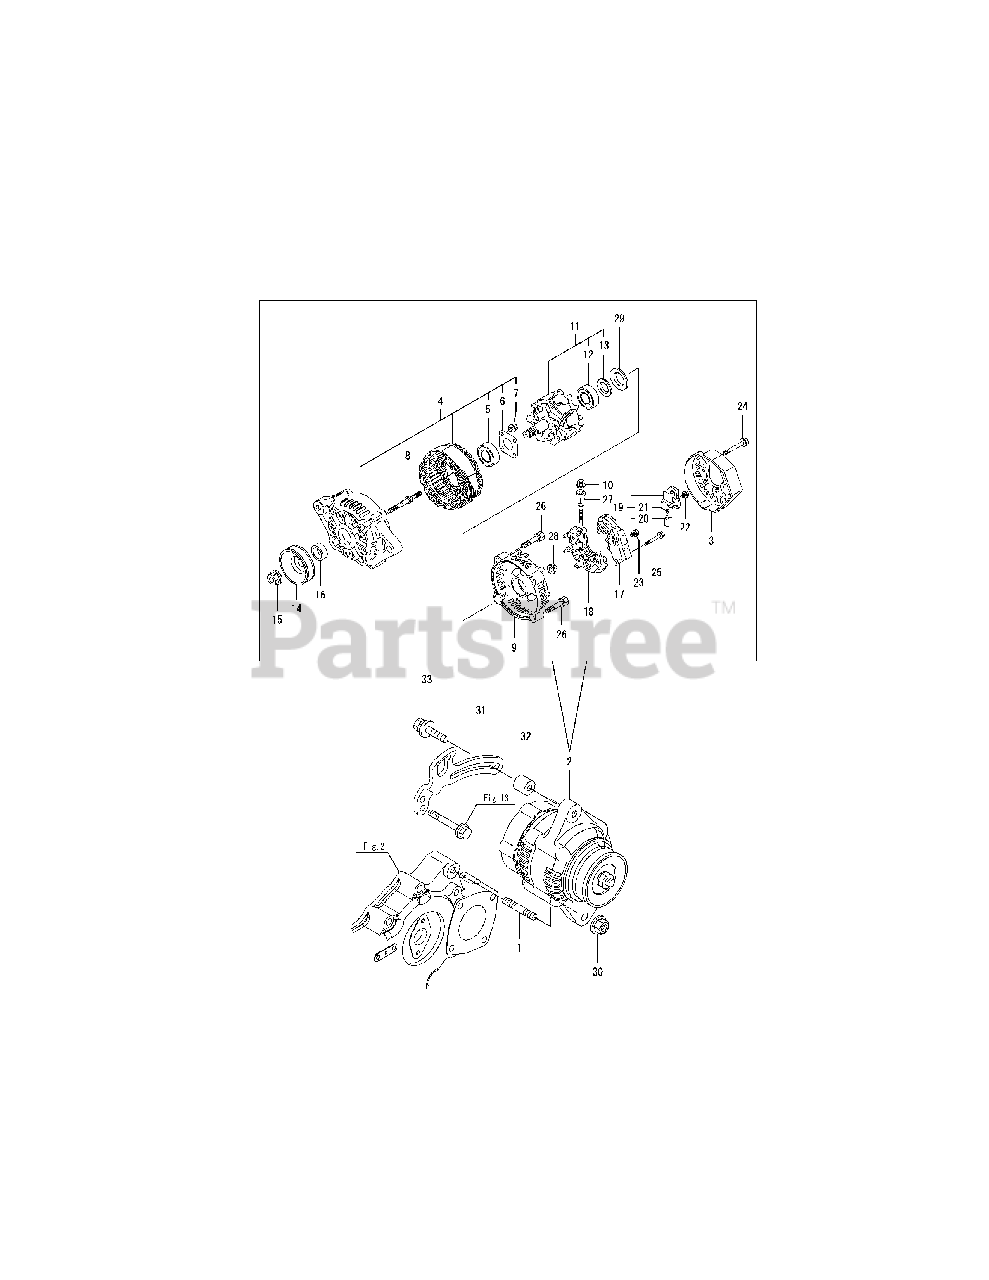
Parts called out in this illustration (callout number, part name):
2	GENERATOR, 12V-40A
4	FLAME ASSY, DRIVE
6	PLATE, RETAINER
9	FLAME ASSY, REAR
13	COVER, BEARING
17	REGULATOR ASSY
27	BUSH, INSULATION
29	WASHER, THRUST
31	ADJUSTER, BELT
33	BOLT, ADJUSTER
